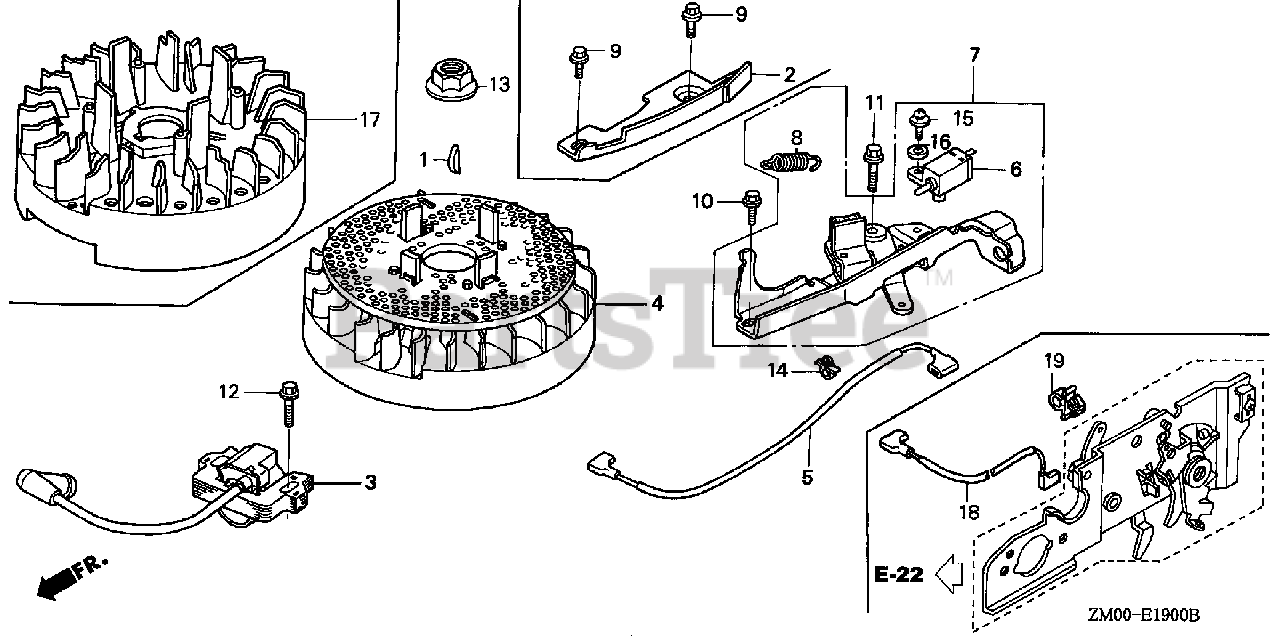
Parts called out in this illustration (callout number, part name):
1	KEY, SPECIAL WOODRUFF (25X18)
2	PLATE, SIDE
3	COIL ASSY., IGNITION
9	BOLT, FLANGE (6X12) (CT200)
12	BOLT, FLANGE (6X20) (CT200)
13	NUT, SPECIAL (14MM)
17	FLYWHEEL
